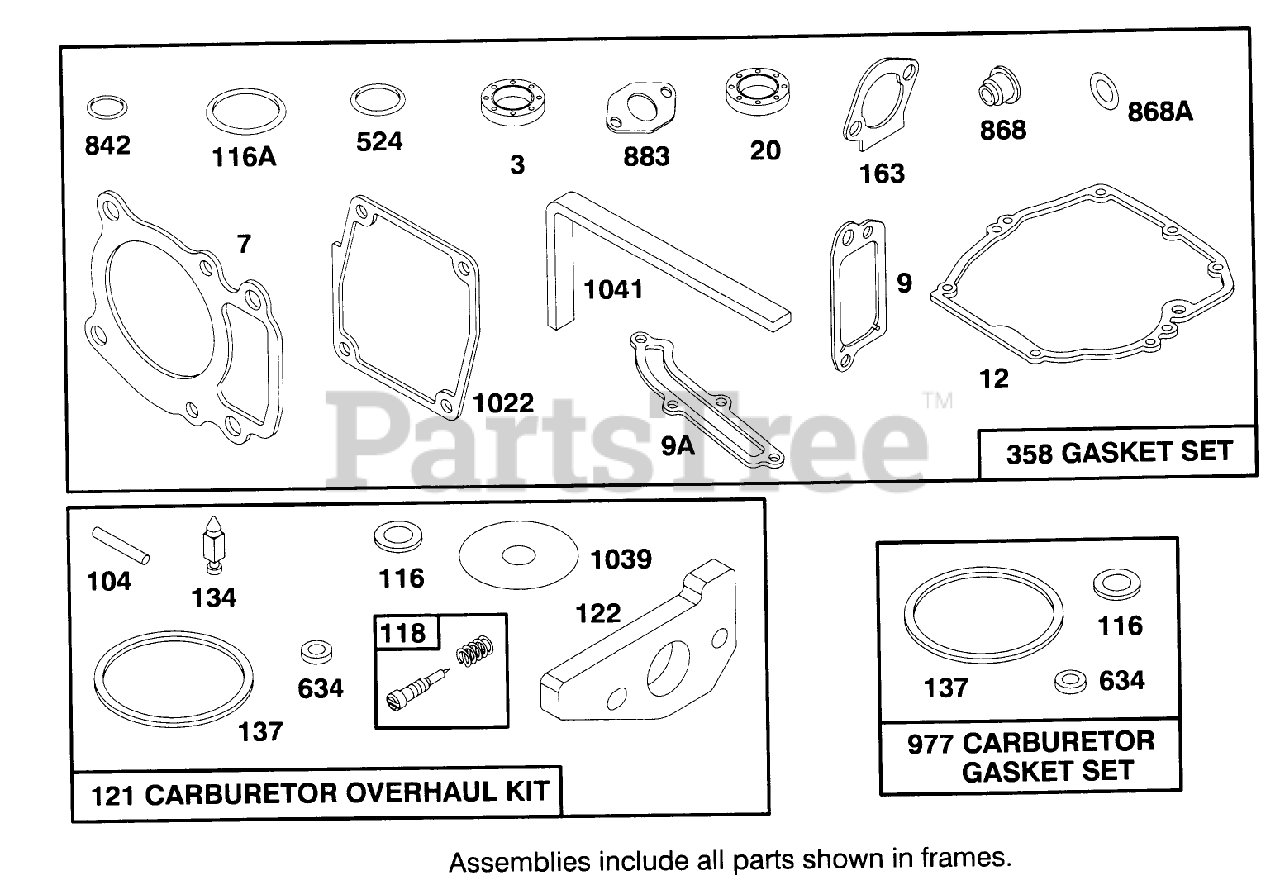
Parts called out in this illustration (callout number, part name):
7	CYLINDER HEAD GASKET
12	GOVERNOR/OIL SLINGER
20	SEAL-OIL
116	SEALING GASKET
116A	O RING SEAL
118	VALVE KIT - NEEDLE
121	CARBURATOR OVERHAUL KIT
122	ADAPTER ASSEMBLY
134	VALVE-FLOAT
137	FLOAT BOWL GASKET
163	AIR CLEANER GASKET
358	GASKET SET
524	O-RING
842	O-RING
977	CARBURATOR GASKET SET
1022	ROCKER COVER GASKET
1039	VENT TUBE
